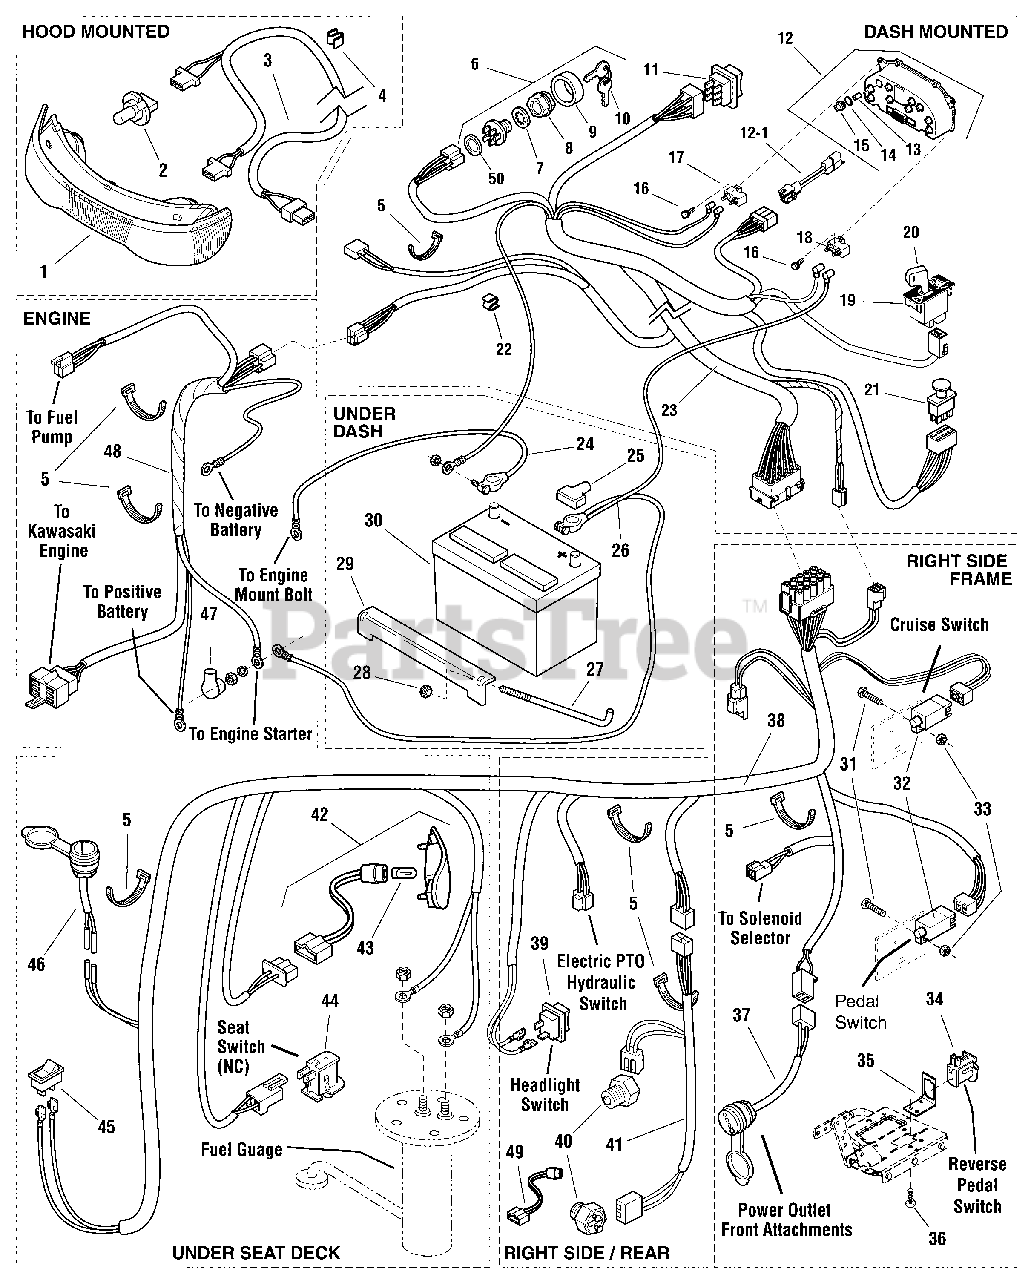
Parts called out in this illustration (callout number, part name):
1	HEADLIGHT ASSEMBLY
2	BULB, Headlight Halogen
3	HARNESS, Wiring, Headlight
4	CLIP, Wire
5	TIE, Self Locking
6	SWITCH ASSEMBLY, Ignition
7	LOCKWASHER, Internal Tooth
8	NUT, Hex, Flange, 5/8-32, Ignition Switch Die Cast
9	COVER, Ignition Switch
10	KEYS, Set of 2
11	SWITCH, Electrical Lift
12	PANEL, Instrument Air Cooled
12	PANEL, Instrument Liquid Cooled
12-1	HARNESS, Jumper, Instrument Panel
13	BULB, Instrument Panel
14	SEAL, Lamp Socket Plug
15	HOLDER, Bulb (Includes Ref. No. 14)
16	SCREW, Hex Washer Head, 12-24 x 5/8
17	BREAKER, Circuit 12Volt, 10Amps
18	BREAKER, Circuit 12Volt, 20Amps with Tab 9/32
19	SWITCH, RMO Module Only
20	KEY, RMO Module, Plastic
21	SWITCH, PTO Push/Pull Symbols
23	HARNESS, Wiring
24	CABLE, 1 Ring, 1 Battery Terminal
25	INSULATOR, Battery Terminal
26	CABLE, 1 Ring, 1 Battery Terminal
28	NUT, Hex Keps, 1/4-20 Conical Washer
29	BRACKET, Battery Hold Down
30	BATTERY, 12 Volt, 6 Cell, 500 Amps
31	SCREW, Hex Washer Head Slot 10-24 x 5/8
32	SWITCH, Push Button, Neutral, Start
33	NUT, Hex KEPS, 10-24
34	SWITCH, Push Button, Reverse Pedal
35	BRACKET, Switch Mount, Reverse Pedal
36	CAPSCREW, Hex Head Taptite, 1/4-20 x 3/8
37	HARNESS ASSEMBLY, Power Outlet
38	HARNESS, Rear
39	SWITCH, Headlights
40	SWITCH, Interlock Ball Check 5/16 LG Thread
41	HARNESS, PTO Lights
42	TAIL LIGHT ASSEMBLY
43	BULB, Tail Light
44	SWITCH, Push Button, Seat
45	SWITCH, Rocker Solenoid, Select
46	OUTLET, 12 Volt
47	BOOT, Cable Terminal
48	HARNESS, Jumper
49	HARNESS, Diode
50	WASHER
